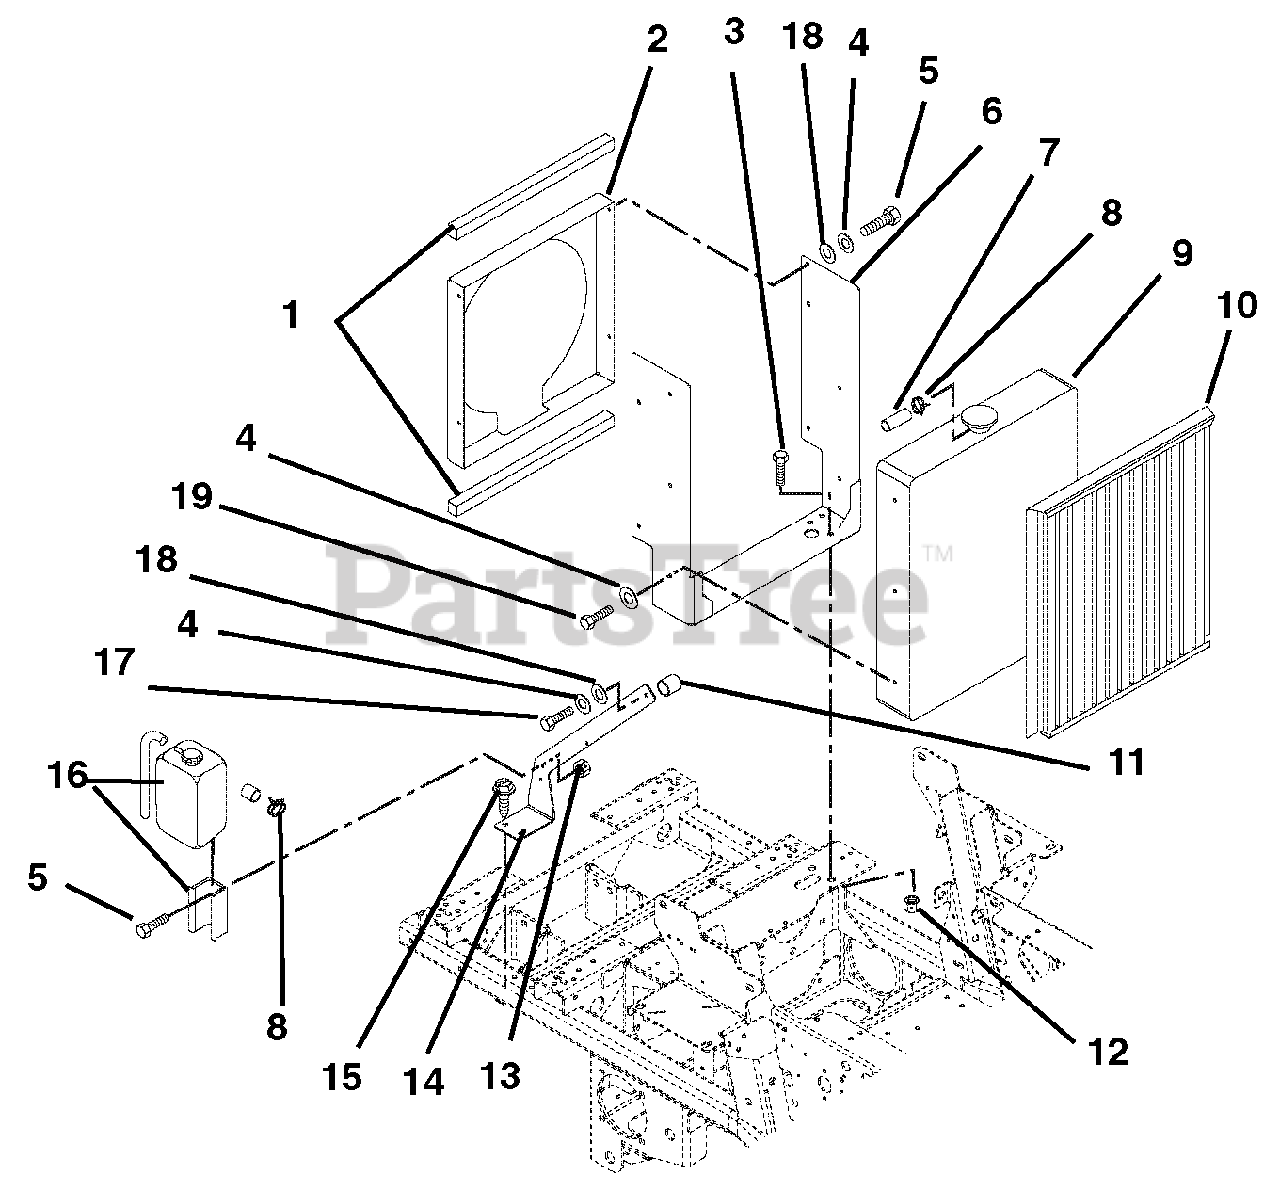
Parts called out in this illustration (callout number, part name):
1	SEAL, TRIM-LOK BULK .06 BBL 1'
2	WMT, RADIATOR SHROUD
3	@BLT-HEX .38-16X1.00 GR5 YWZC
4	@WSHR-LK .25X.062 REG YWZC
5	@BLT-HEX .25-20X.75 GR5 YWZC
6	WMT, RADIATOR MOUNTING BKRT
7	HOSE, .25 LOW-PERM BULK GAS
8	CLAMP, FUEL LINE
9	Radiator (Comes with the engine)
10	SCREEN, RADIATOR (DIESEL)
11	SPACER .328 X .76 X 1.01
12	@NUT-LK-TOP-FLG .38-16 YWZC
13	@NUT-LK-TOP-FLG .25-20 YWZC
14	BRKT, OVERFLOW MOUNTING - BLK
15	@SCR-TAP .38-16X.75 HWH TR YWZ
16	Reservior Overflow (Comes with the engine)
17	@BLT-HEX M6-1.00X45 YWZC
18	@WSHR-FL-STL.281X.62X.065 YWZC
19	@BLT-HEX M6-1X16 YWZC
